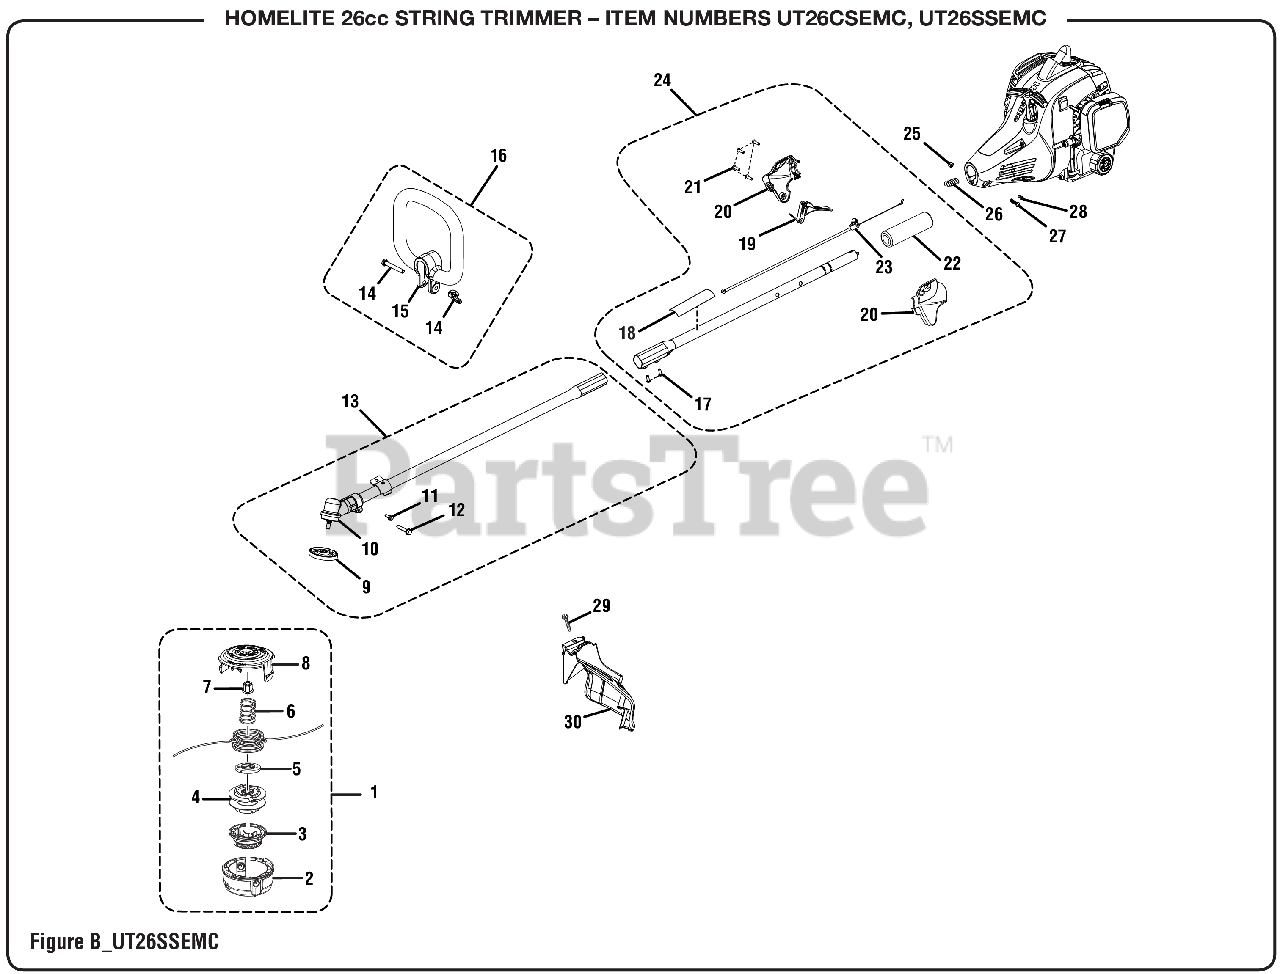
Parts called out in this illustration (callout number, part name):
1	Trimmer Head Assembly
2	Lower Housing
3	Bump Knob (Gray)
4	Spool Assembly
5	String Guide
6	Compression Spring
7	Hex Nut (M8, Left Hand Threads)
8	Upper Housing
9	Flanged Washer
10	Gear Head
11	Screw w/Washer (10-24 x 5/8 in., Hex Hd. T.F.)
12	Screw (1/4-20 x 1-1/4 in., Hex Washer Hd. S.T.)
13	Lower Boom Assembly
14	Fastener Parts Kit
15	Front Handle
16	Front Handle Assembly
17	Set Screw (M5 x 10 mm, Hex Soc. Hd.)
18	Icon Warning Label
19	Throttle Trigger
20	Trigger Handle Assembly
21	Screw (M4 x 20 mm, T20 Torx Pan Hd. T.Fl.)
22	Rubber Grip
23	Throttle Cable
24	Boom Assembly
25	Hex Nut (M6.3 x 1)
26	Compression Spring
27	Screw (M6 x 20 mm, T27 Torx Button Hd.)
28	Screw (M4 x 8 mm, T25 Torx Pan Hd. T.F.)
29	SCREW (#1/4-20 X 1-1/4 in. HEX WASHER HD.)
30	Grass Deflector Assembly
